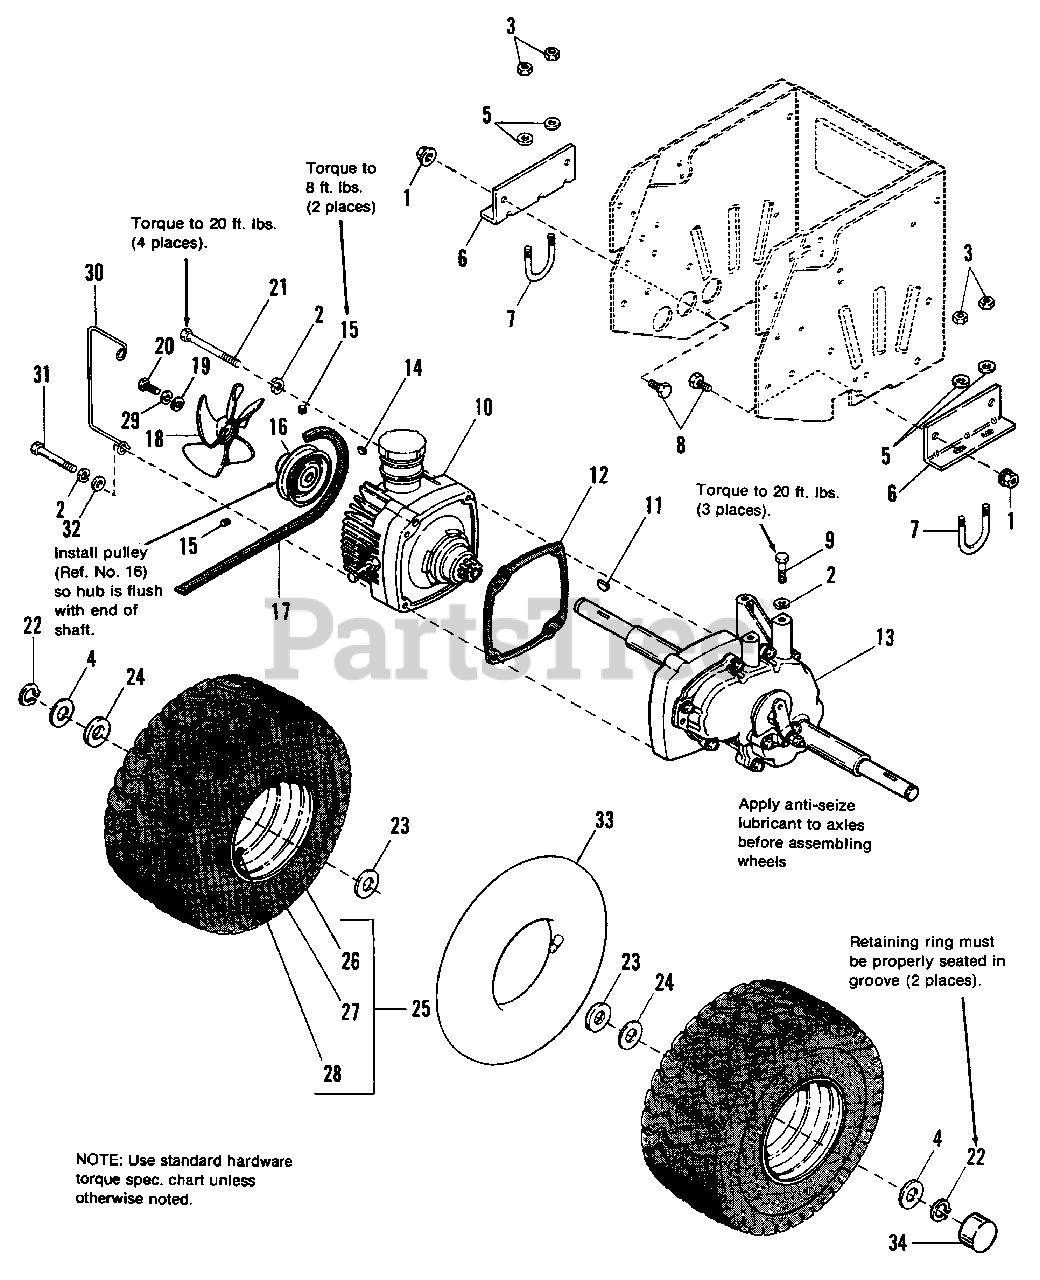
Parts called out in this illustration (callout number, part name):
1	NUT, Hex, Flange Lock, 3/8-16
2	LOCKWASHER, 3/8
3	NUT, Hex, 5/16-18
4	WASHER, 1 x 1-7/8
5	WASHER, 5/16
6	SUPPORT, Transmission
7	"U" BOLT, Axle
8	CAPSCREW, Hex, 3/8-16 x 1
9	CAP, Hub, Threaded
10	TRANSMISSION, Hydrostatic (See pages 18 & 19 for parts list)
11	KEY, Woodruff, #18, 1/4 x 1-1/4
13	GEAR REDUCTION & DIFFERENTIAL ASSY.
14	KEY, Woodruff, #3, 1/8 x 1/2
15	SETSCREW, Hex Pt., Cup, 1/4-28
16	PULLEY, Transmission
17	BELT, "V" Drive, Transmission
18	FAN, 6-3/4" Diameter
19	WASHER
20	CAPSCREW, Hex, 1/4-2 x 1/2
21	CAPSCREW, Hex, 3/8-16 x 3
22	RING, Retainer
23	WASHER, 1 x 1-3/4, Thrust
24	WASHER, Plain, 1 x 1-3/4, Plated
25	WHEEL & TIRE ASSY.
25	WHEEL & TIRE ASSY., 20 x 8-10 (Used on 1691032 & 1691234 only)
26	TIRE, 20 x 10 x 10 (Used on (1691033, 1691235, 1691362 & 1691473 only)
26	TIRE, 20 x 8 x 10 (Used on 1691032 & 1691234 only)
27	WHEEL ASSY.
28	VALVE STEM & CAP
29	LOCKWASHER, 1/4
30	BELT STOP
31	CAPSCREW, 3/8-16 x 3-1/4
32	WASHER, 3/8
33	TUBE (For Service Only. See Note Below)
